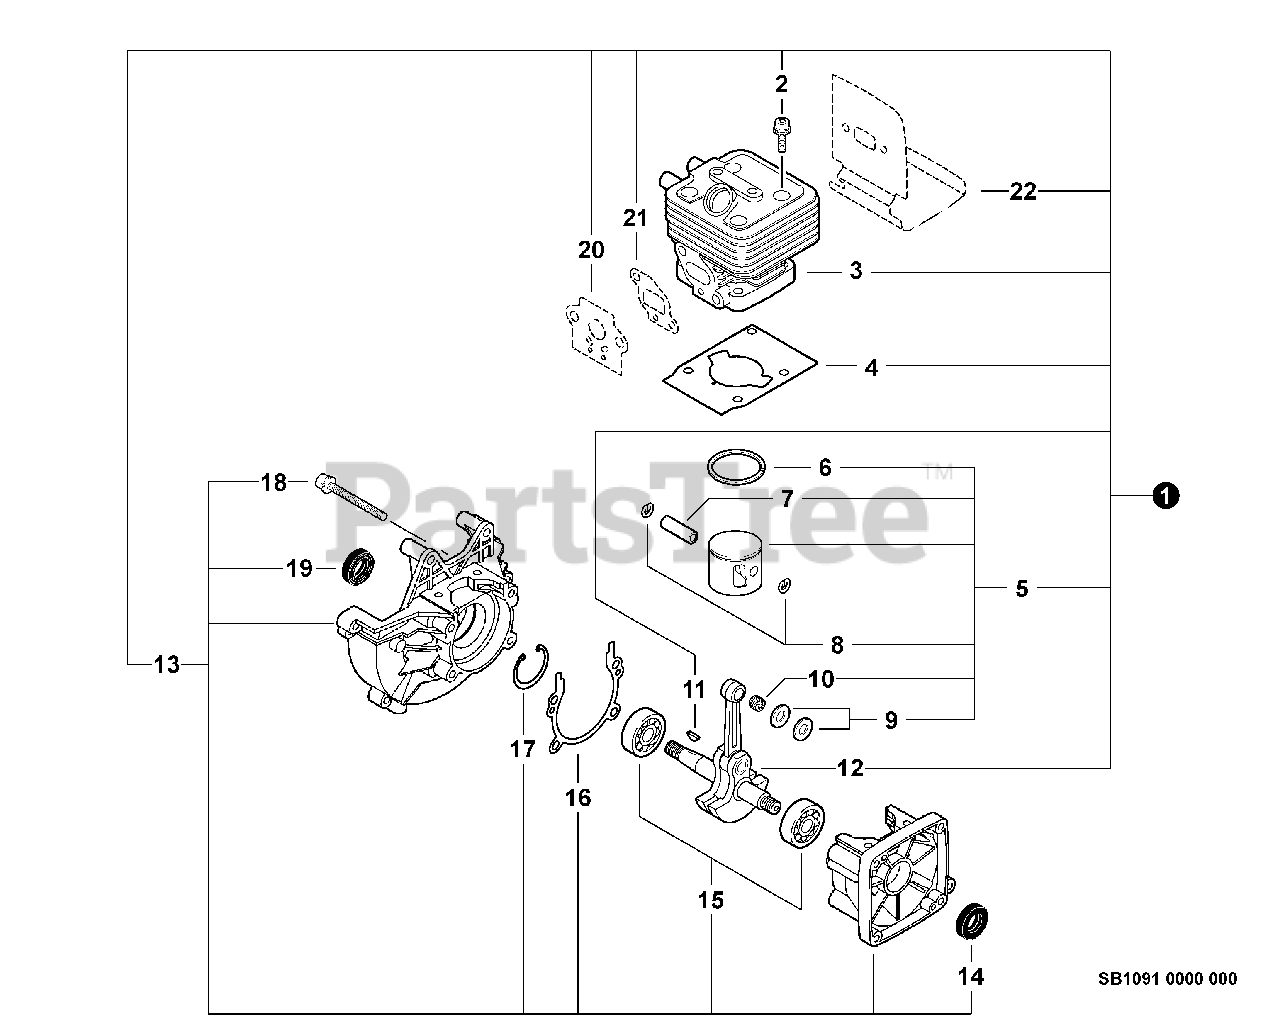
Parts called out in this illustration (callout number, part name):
1	SHORT BLOCK
2	SCREW 5×25
3	CYLINDER
4	GASKET, CYLINDER
5	PISTON KIT
6	RING, PISTON
7	PIN, PISTON
8	RING, SNAP
9	WASHER, THRUST 8
10	BEARING, NEEDLE 9
11	KEY, WOODRUFF
12	CRANKSHAFT ASSY
13	CRANKCASE KIT
14	SEAL, OIL 12
15	BEARING, BALL - 6201 C3
16	GASKET, CRANKCASE
17	RING, SNAP Ø32
18	BOLT 5×28
19	SEAL, OIL 12
20	GASKET, INTAKE
21	GASKET, INTAKE
22	SHIELD, EXHAUST
